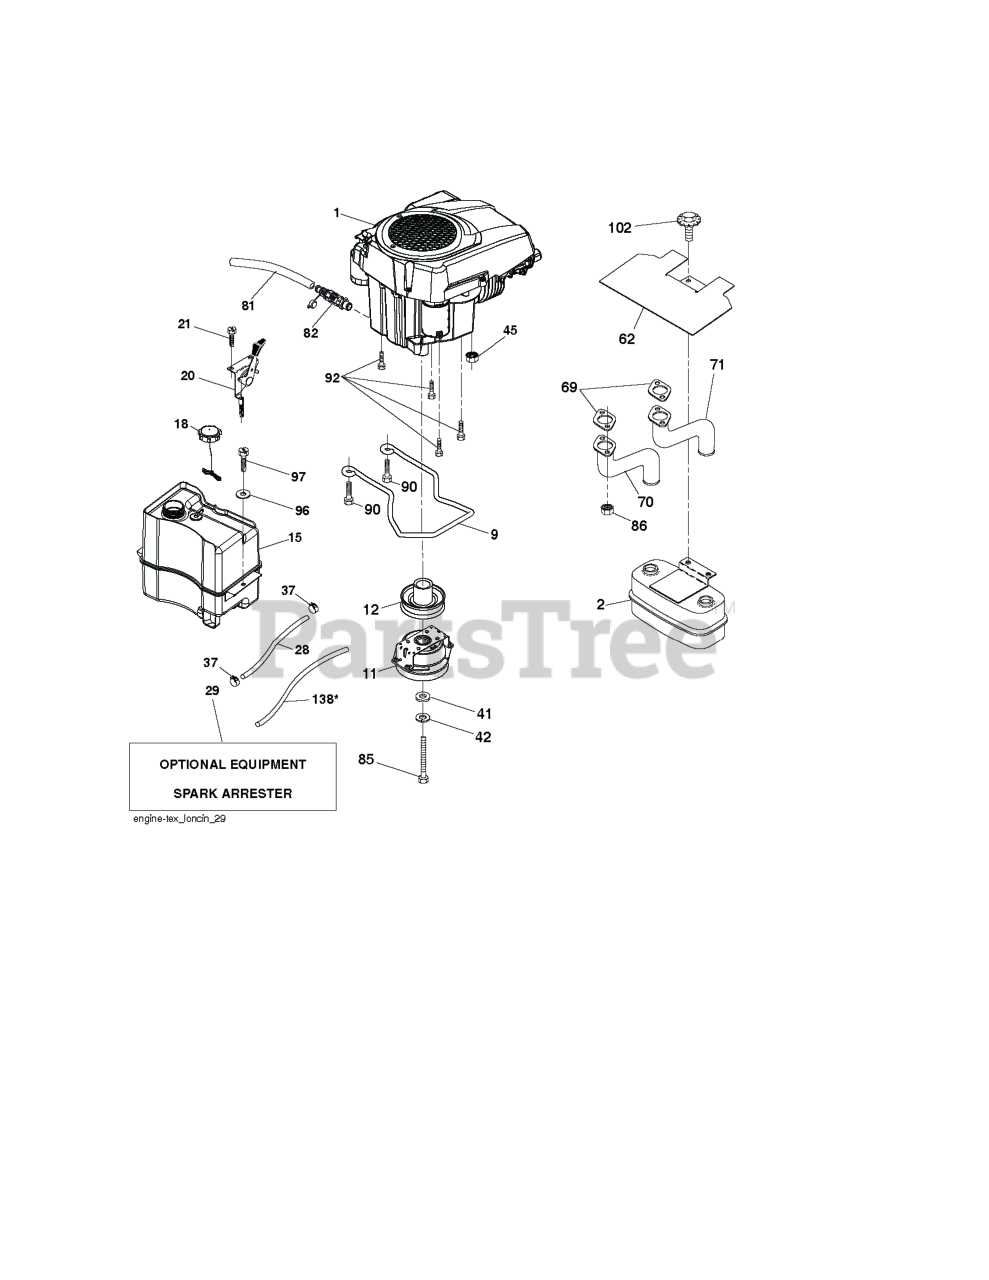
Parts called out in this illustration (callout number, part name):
2	MUFFLER.ASM.TWIN.MNTG.BRACKET
11	CLUTCH.OGURA.5.0PD.GT1.5A-EH07
12	PULLEY.ENGINE.TUFFTORQ
15	FUEL TANKS
15	TANK.ASSEMBL.2.5GAL.NON-EPA
18	CAP.FUEL.2 WAY VENT
20	CONTROL.TH/CK.COBRA.B&S.TWN.BK
28	LINE.FUEL.20
29	KIT.SPARK ARRESTOR 794945 B&S
37	HOSE CLAMP
45	NUT HEXAGON WITH FLANGE, SERRA
62	SHIELD.HEAT.MUFFLER
81	TUBE, DRAIN OIL ASM.
82	VALUE.OIL.DRAIN
85	BOLT.HEX.7/16-20X3.75.GR5.RED
86	NUT.HEX.FLANGE.TOPLOCK
90	SCREW 3/8-16X1
92	SCREW 3/8-16X1
97	SCREW HEXWSHR 1/4-20X3/4
102	SCREW
